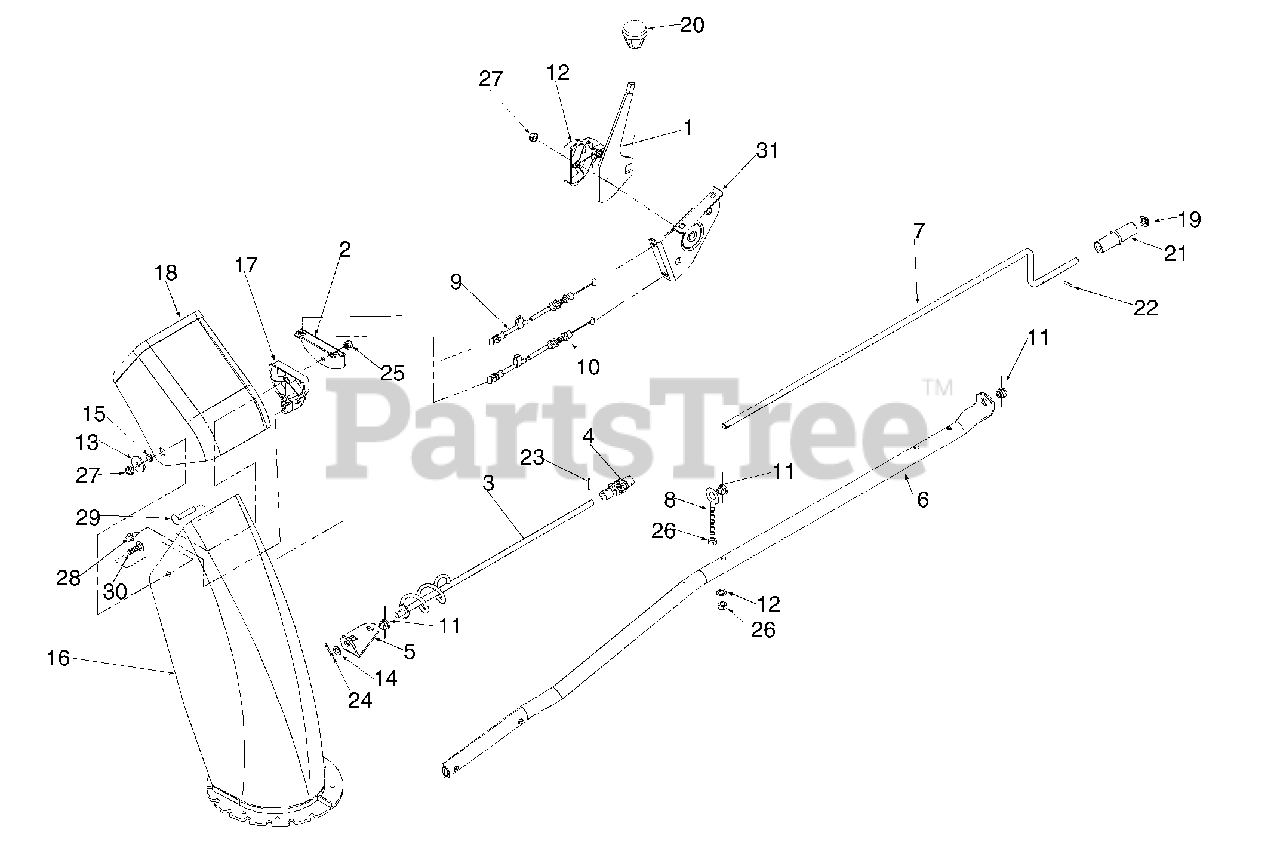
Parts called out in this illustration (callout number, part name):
3	CHUTE CRANK ASSY 18.0 LG - RH
4	BLOCK ASS:JOINT
8	EYE BOLT 5/16-18 X 3.0 LG
9	CBL:CHUTE:W/CULP, 66 LG
10	CBL:CHUTE 66 LG
11	PLASTIC BUSHING .380 ID
12	WASH:BELVL:.340 ID X .872 OD
12	Chute Tilt Cable Guide
13	WASH:FL:.344 ID:1.125 OD:.12
14	FL-WASH .385 ID X .62 OD X .06
15	SPCR:CHUT:PIVOT
16	CHUT:LWR:EXTENDED 6" DIA
17	Chute Tilt Cable Guide
18	6" DIA UPPER CHUTE
19	CAP:PUSH X 3/8 ROD
20	KNOB:SHFT:1.60 OD X 1.56
21	KNOB:CRK:1.00 DIA X 3.2 CHUTE
22	PIN:ROLL:1/8 OD :.63
23	SPIROL PIN - 1/8 DIA X .812 LN
24	PIN:COT:3/32 X .750
25	NUT:HX:5/16-18:GRC:LOCK
26	NUT:5/16-18:GRA:HX
27	NUT:LOCK:5/16-18:CEN
28	SCR:1/4-14:.625:HXINDWSH
29	CARRIAGE BOLT 5/16-18 X 1.75
30	SCR:CARR:5/16-18:1.00
